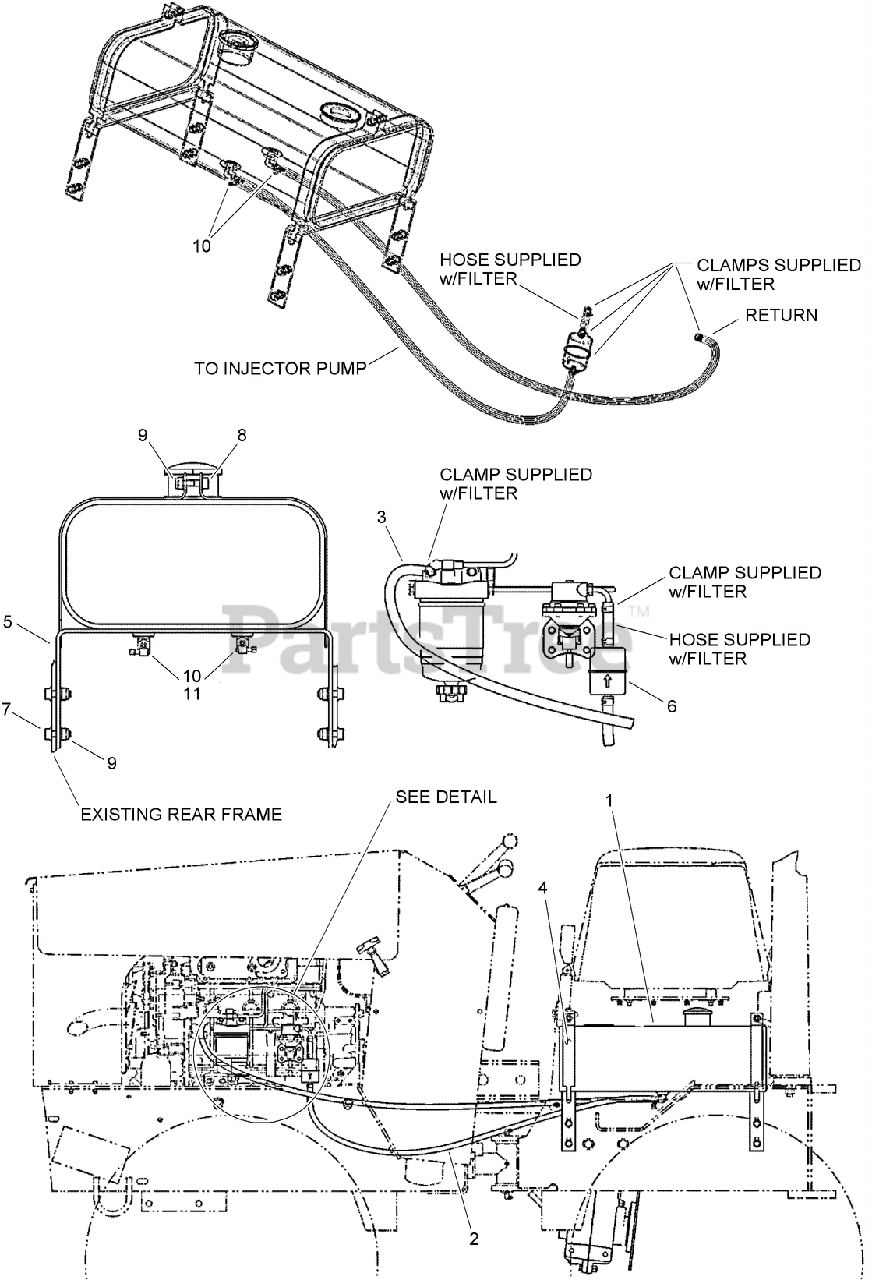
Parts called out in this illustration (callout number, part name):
1	TANK-FUEL
2	TANK ASSEMBLY - Fuel
3	TANK ASSEMBLY - Fuel
4	HOSE - Fuel Line
5	STRAP - Fuel Tank
6	BRACKET - Fuel Tank Mounting
7	SCREW-HH
8	SCREW, METRIC FLANGE FULL - M8 x 25
9	NUT-TORQUE, PREVAILING
10	CLAMP-Hose Type M #04
11	STEM-90 (BARB HOSE)
